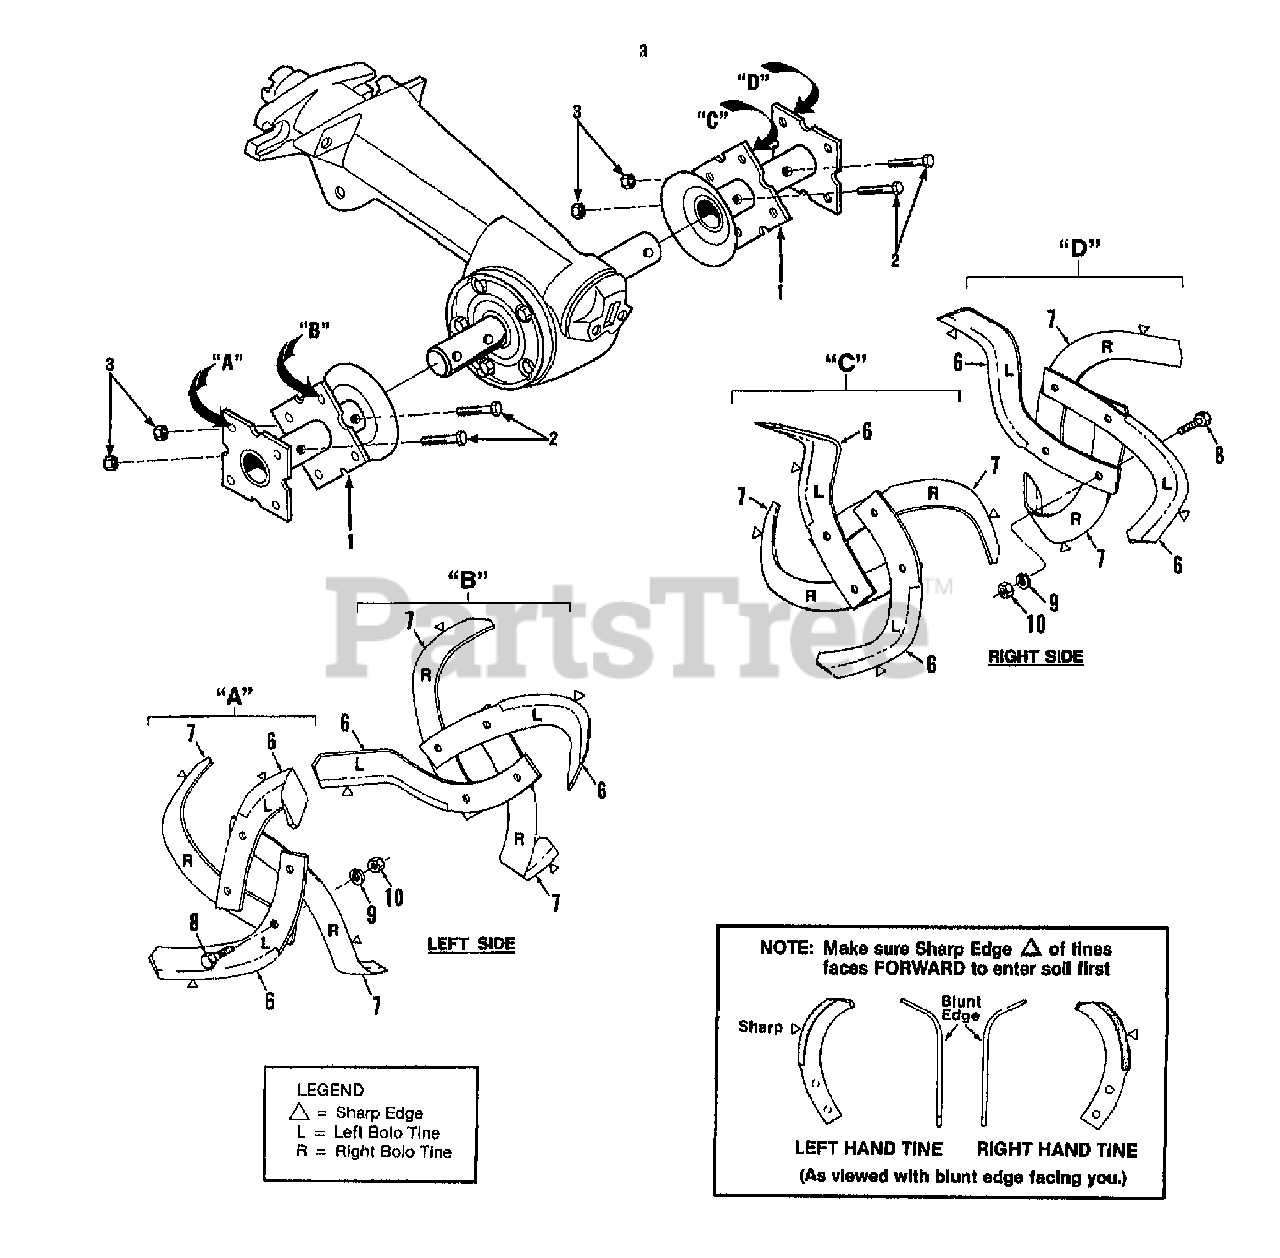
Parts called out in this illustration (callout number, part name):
1	HOLDER-TINE HORSE (RED)
2	SCR-HH 3/8-16X2.00 G8
3	NUT-H/LK 3/8-16
4	THIS REF. NO. NOT USED
5	THIS REF. NO. NOT USED
6	TINE-BOLO LT W/HDW(INCL. TWO EACH OF REF. NO.'S 8,9 AND 10)
7	TINE-BOLO RT W/HDW(INCL. SAME HARDWARE AS REF. NO.6)
8	SCR-HH 3/8-16X1.0 G5 ZP
9	WASHER-LK .375 @ DEPL
10	NUT-HEX 3/8-16 ZP
